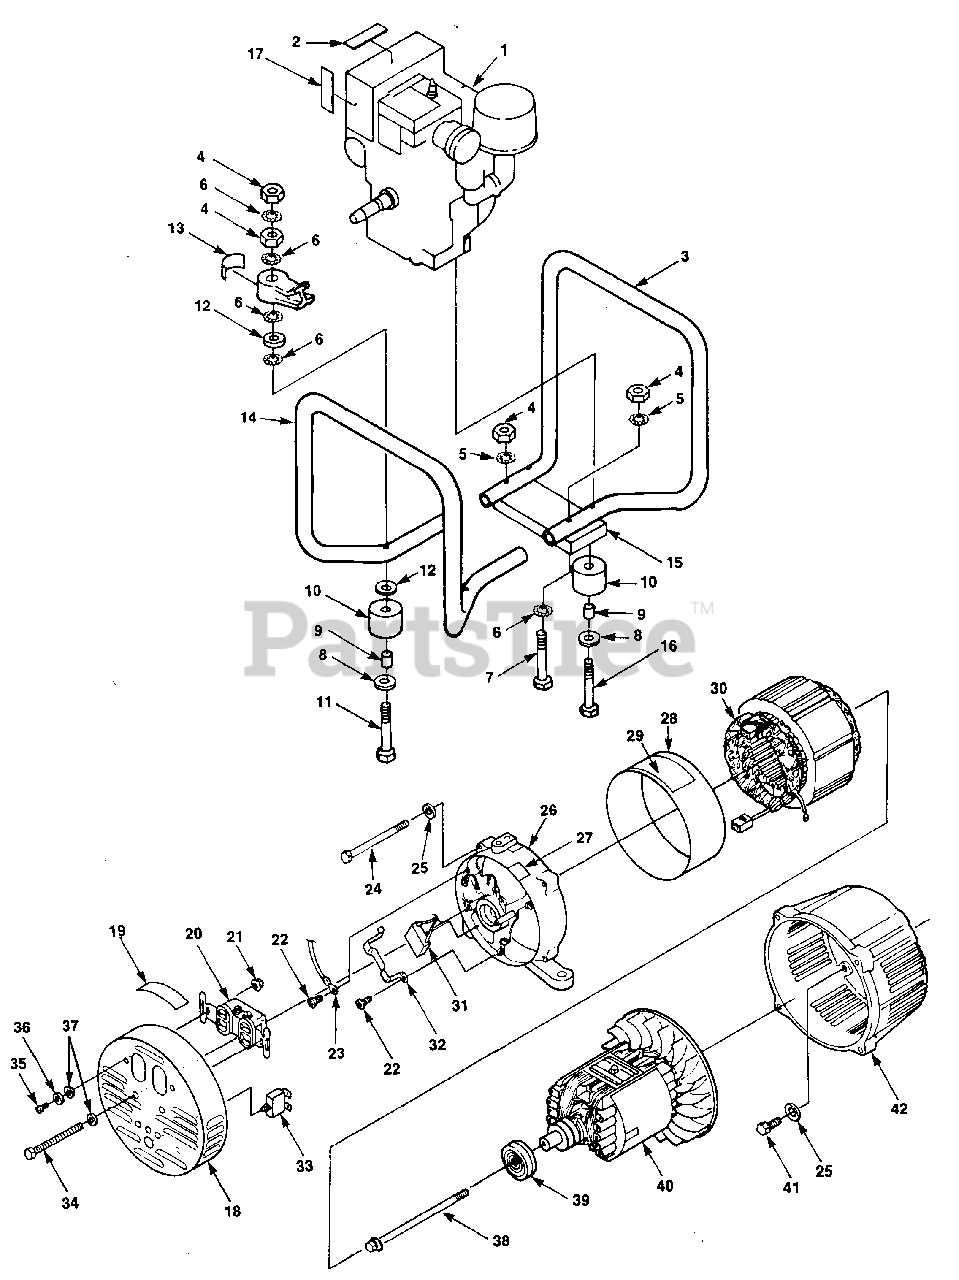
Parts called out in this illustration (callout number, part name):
2	DECAL- Warning
3	MEMBER- Frame
4	NUT- Hex (5/16-18)
5	WASHER- Lock int. (5/16")
6	WASHER- Lock ext./int.
7	BOLT- Engine (rear)
8	WASHER- Flat (5/16")
9	SPACER- Foot
11	SCREW- Cap hex. hd. (5/16-18 x 3")
12	WASHER- Flat (5/16")
13	DECAL- Ground
14	FRAME- Member
15	PLATE- Frame
16	BOLT- Engine (front)
17	DECAL- Caution
18	END COVER
19	DECAL- Warning
20	RECEPTACLE (120V) (HL2500)
21	NUT- (120V receptacle)
22	SCREW- (m5 x 12mm)
23	LEAD- Electrical
24	BOLT- Stator
25	WASHER- Lock ext./int.
26	END BELL
28	COVER- Stator
29	DECAL- Output
31	CAPACITOR
32	HOLDER- Capacitor
33	BREAKER- Circuit (20 amp)
34	BOLT- Cover (m5)
35	SCREW- (120V receptacle)
36	WASHER- Lock
37	WASHER- Flat
38	BOLT- Rotor
39	BEARING- Ball
41	SCREW- Hex hd. (3/8-16 x 1")
